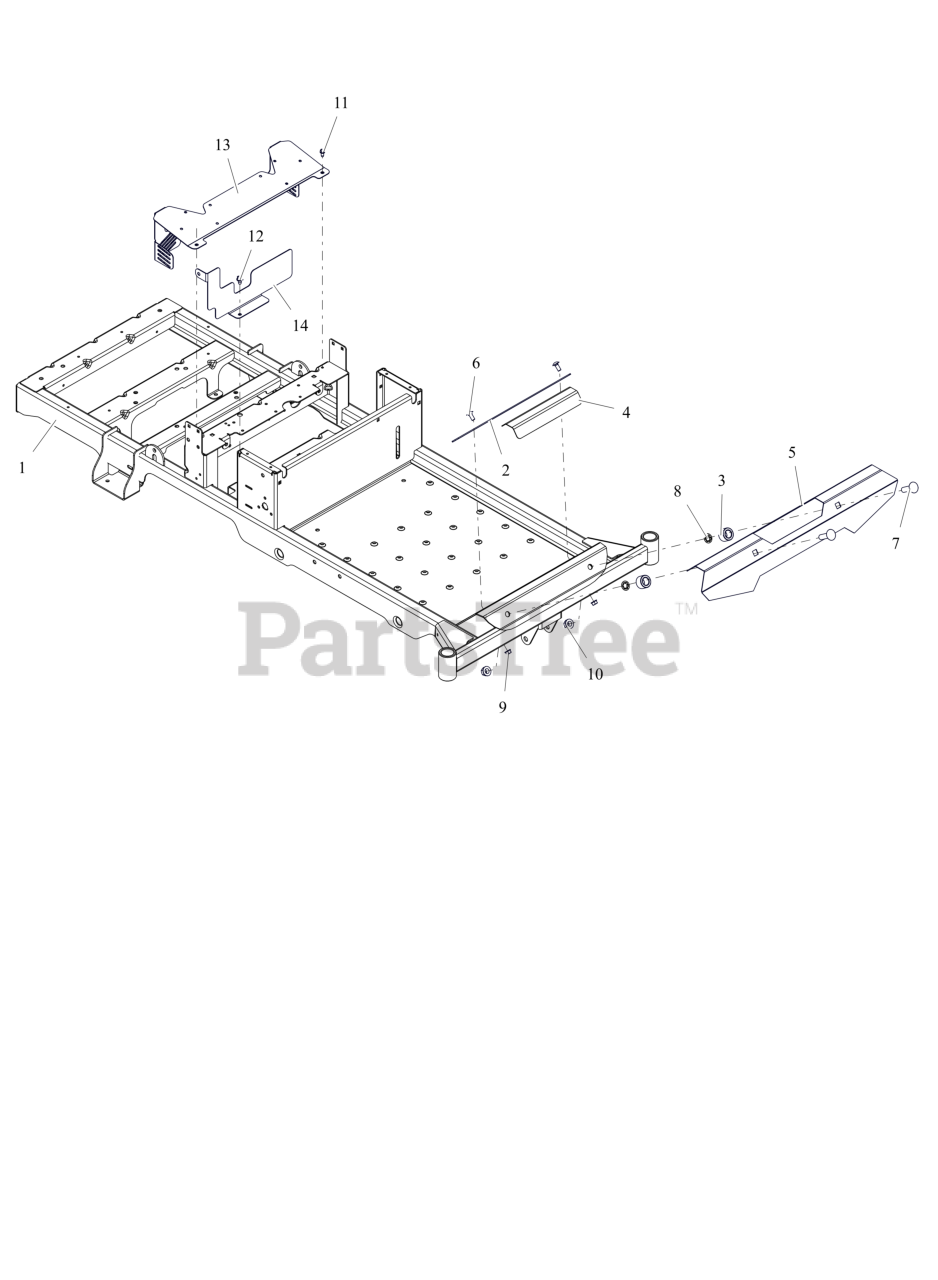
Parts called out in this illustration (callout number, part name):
1	KIT, EDGE FRAME W/DECALS
2	GRIP, ADHESIVE (1" X 16" BLK)
3	TUBE, UPPER CONTROL PIVOT
4	GRIP, STEP
5	FOOTREST, (ORANGE)
6	BLT, RHSSN.31-18X.750 G5 ZCC
7	BLT,RHSN .50-13X1.75 G5 ZCC
8	NUT-PUSH, .50
9	NUT,LK-CTR-FLG .31-18 GF ZCC
10	NUT-LK-CTR-FLG .500-13 GG ZCC
11	SCR-TAP .25-20X.50 HWH ZCC
12	SCR,TAP .312-18X.50 HWH TR ZCC
13	PLATE, FAN GUARD CE (BLACK)
14	SHIELD, SEAT TRANSAXLE CE (BLACK)
